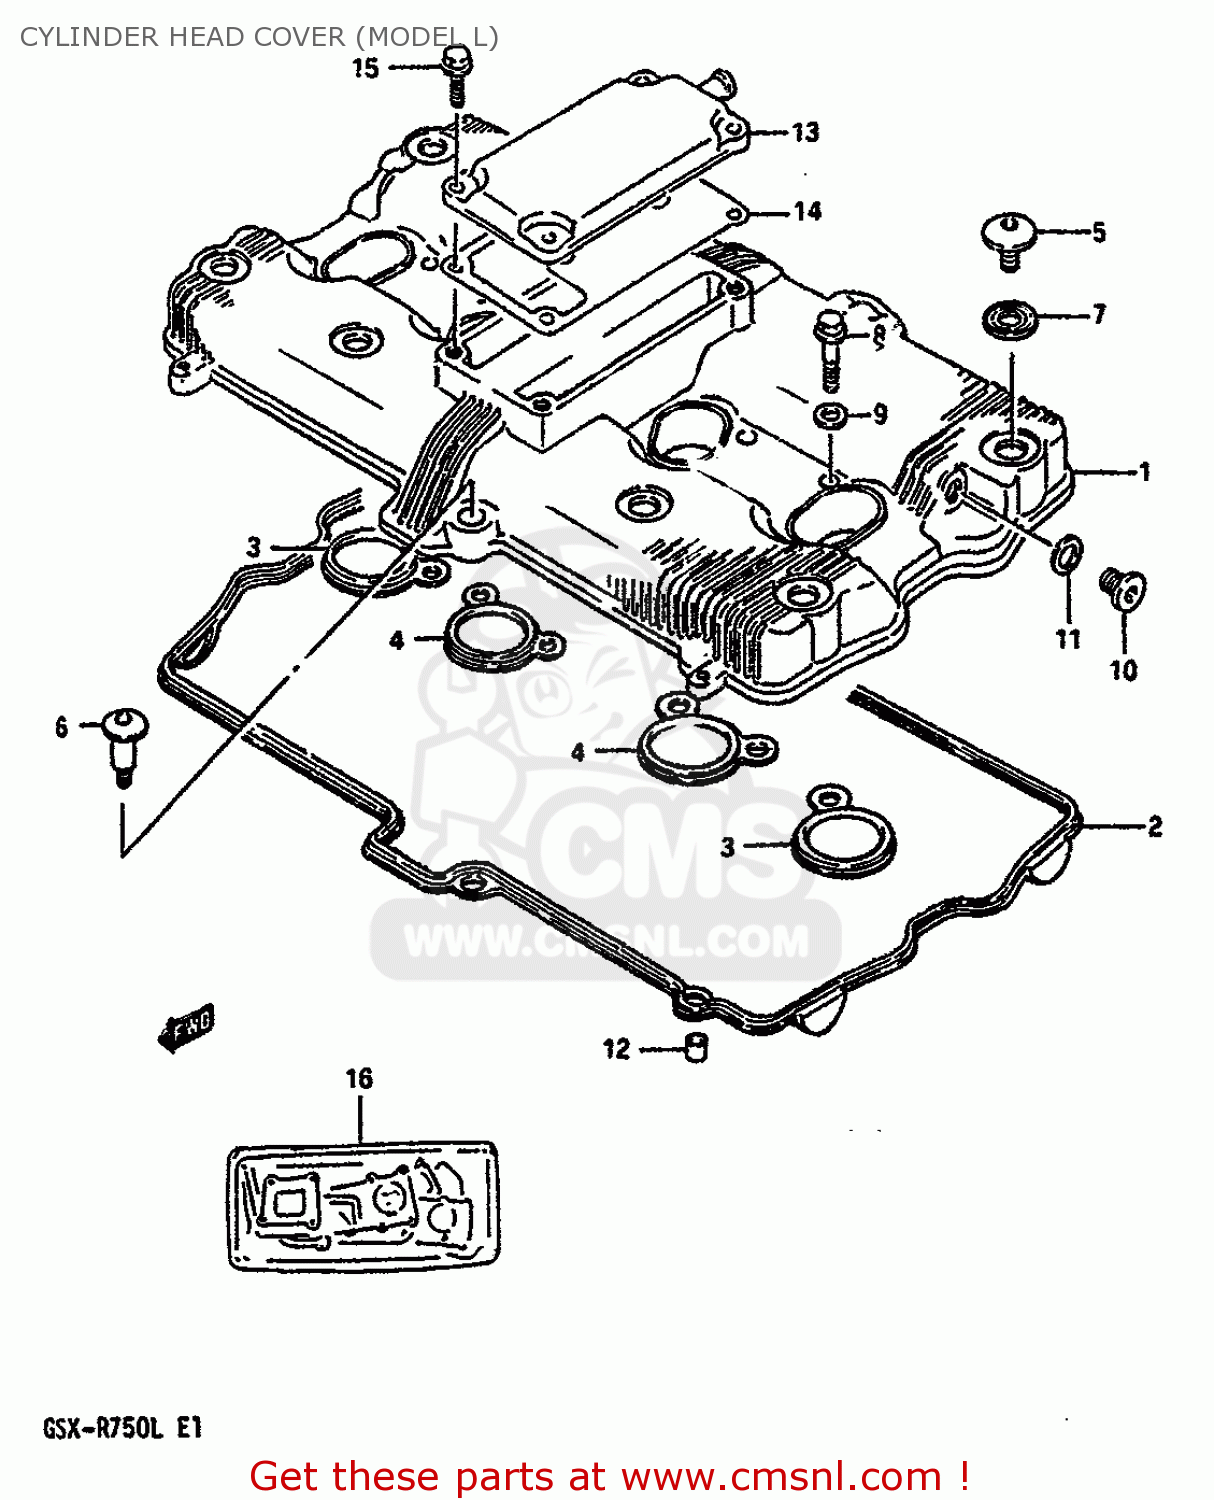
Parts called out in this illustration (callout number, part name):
1	COVER,CYLINDER HEAD
2	GASKET,CYLINDER HEAD COVER (NAS)
3	GASKET,HEAD COVER NO.2 (NAS)
4	GASKET,HEAD COVER NO.3 (NAS)
5	BOLT(7X17.5)
6	BOLT(7X31)
7	WASHER
8	BOLT,UNION 8X35
9	GASKET 8.2X14X1 (NAS)
10	PLUG(L:12)
11	GASKET(12.1X16.2X3.7) (NAS)
12	PIN
13	COVER,BREATHER
14	GASKET (NAS)
15	BOLT
16	GASKET SET
